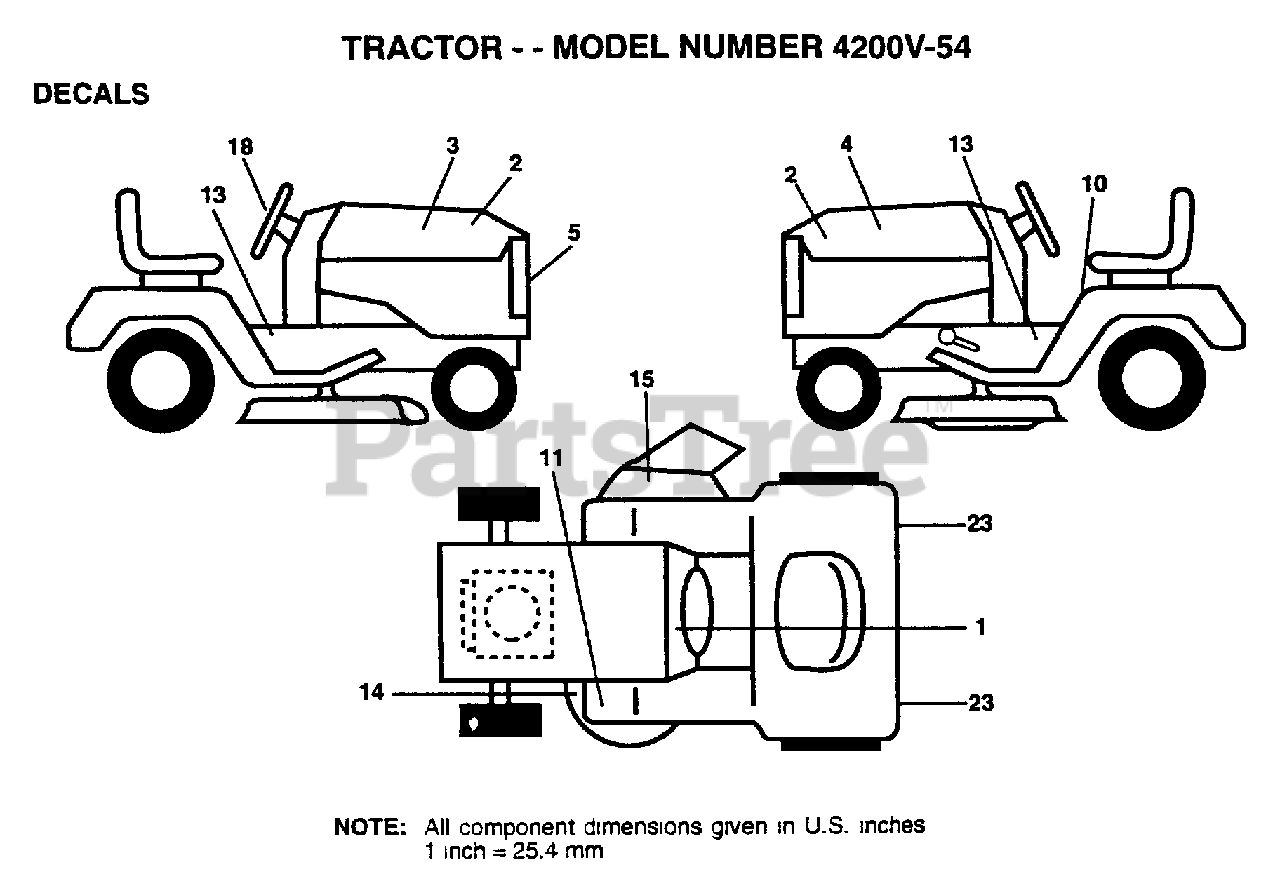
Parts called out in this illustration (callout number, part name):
1	DECAL.DASH.INST.
2	NAMEPLATE LOGO
4	HOOD DECAL LH
5	GRILL DECAL
10	DECAL
13	DECAL.CHASSIS
14	"DECAL.V.BELT.44"""
15	"DECAL, WARNING"
23	REFLECTOR-TAIL YT
